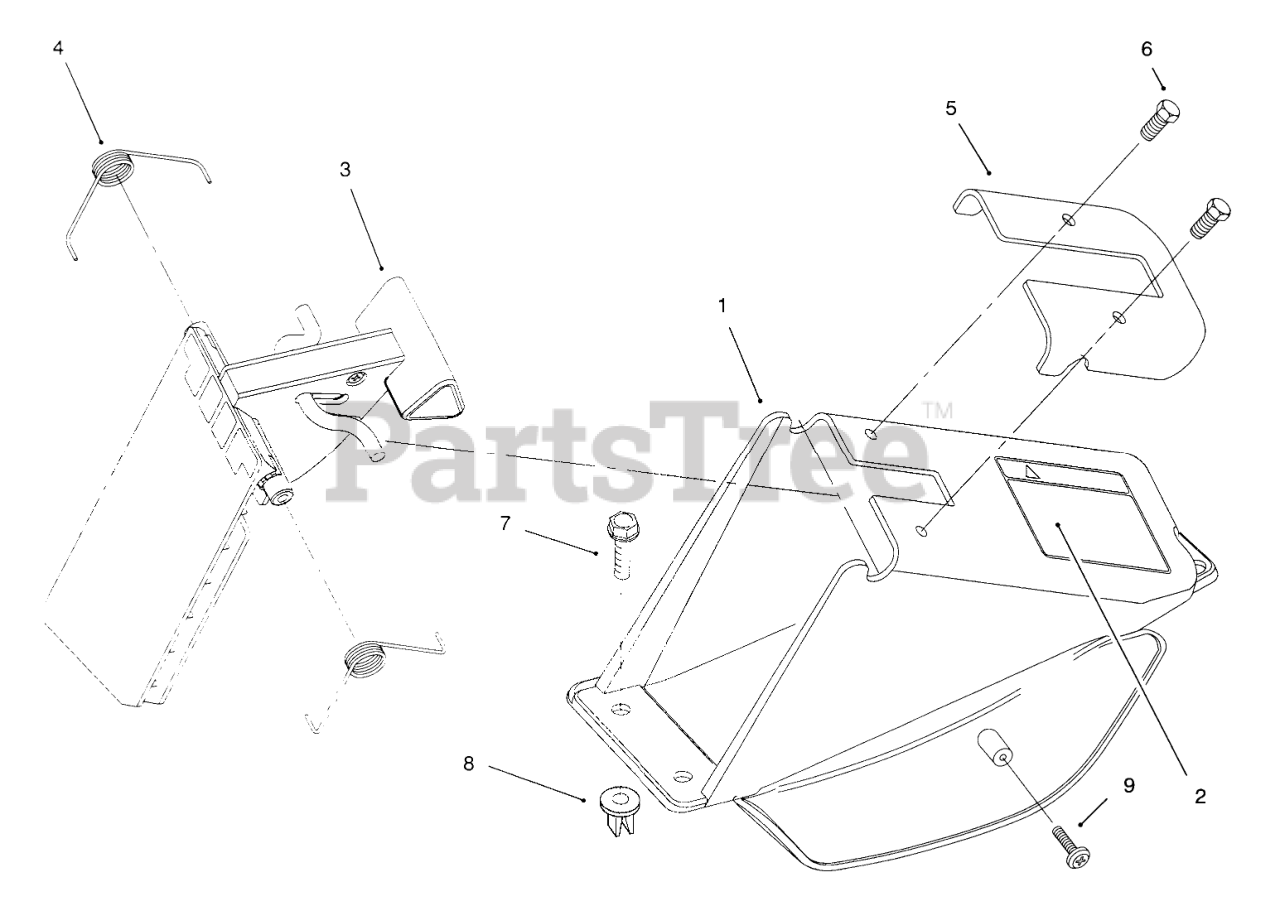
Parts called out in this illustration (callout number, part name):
1	CHUTE - DISCHARGE
2	DECAL - CAUTION DOOR
3	ASM - DISCHARGE DOOR
4	SPRING-DOOR, RH
5	Plate-Discharge
6	SCREW-PLASTITE
7	SCREW-HWH
8	NUT - CLIP
9	SCREW-PPH
